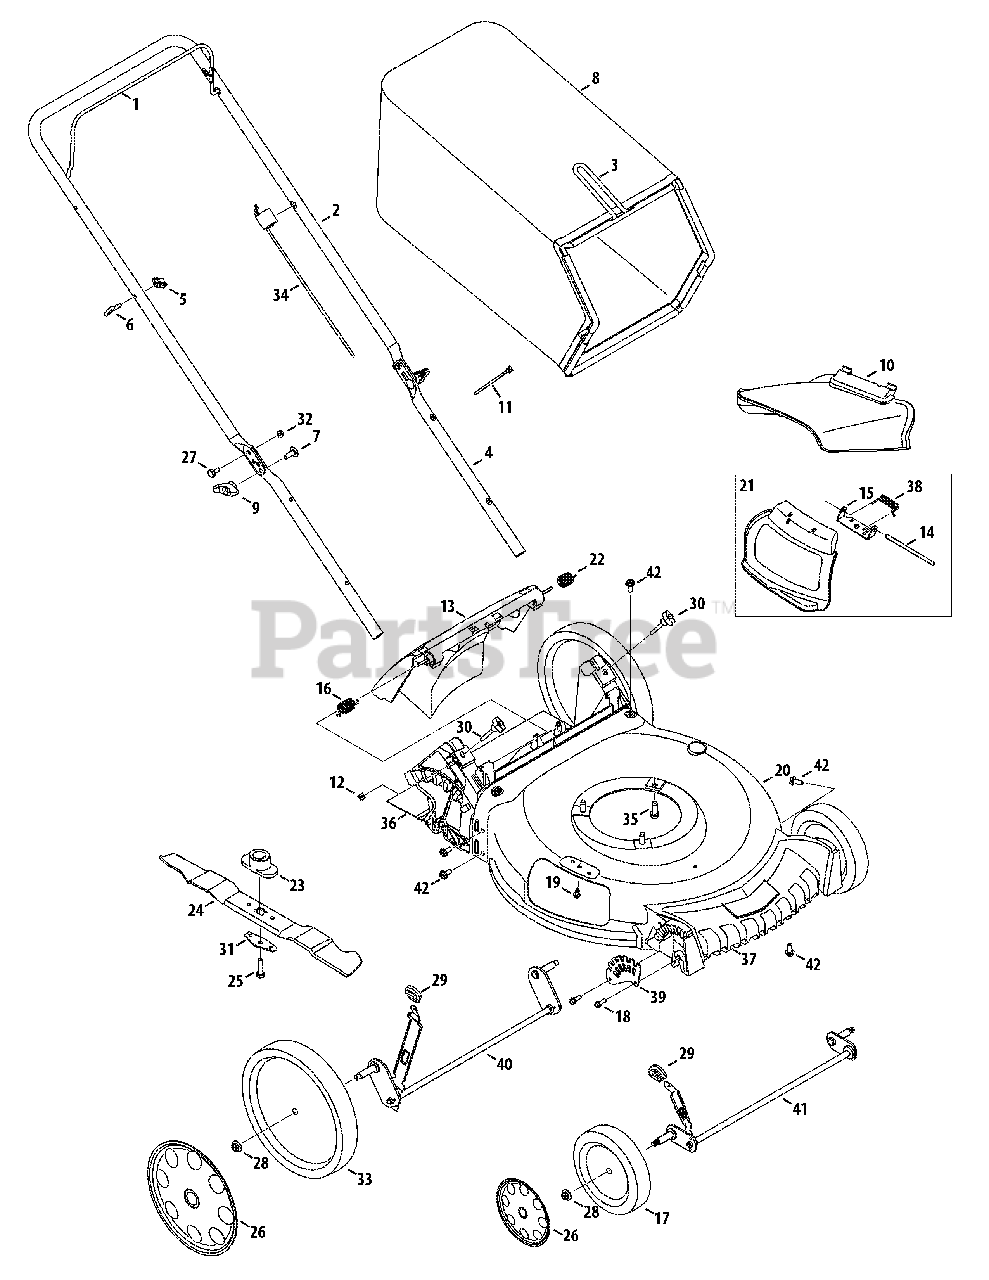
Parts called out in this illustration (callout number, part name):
1	Blade Control
2	Upper Handle
3	Grass Catcher Frame
4	Lower Handle
6	Rope Guide
7	Carriage Screw, 5/16-18
8	Grass Bag
10	Side Chute w/Flap
11	Cable Tie
12	Nut, Sq., 1/4-20
13	Rear Discharge Door & Baffle Assembly-Generic
13	Rear Discharge Door & Baffle Assembly-Lowes
14	Hinge Pin
15	Chute Deflector Bracket
16	Torsion Spring - RH
17	Front Wheel
18	Screw, 1/4-15 x .750
19	Screw, 1/4-20 x .500
20	Deck, 21"
21	Hinged Mulch Plug Assembly
22	Torsion Spring - LH
23	Blade Adapter
24	Mulching Blade
25	Screw , 3/8-24 x 1.50
26	Hub Cap - Front
26	Hub Cap - Rear
27	Sldr. Screw, .375 x .126 x 1/4-20
28	Flange Lock Nut, 3/8-16
29	Adjustment Lever Knob
30	Wing Nut
31	Blade Bell Support
32	Nut, Flange Lock, 1/4-20
33	Rear Wheel
34	Control Cable
35	TT Sems Screw, 3/8-16 x 1.0
36	Trail shield
37	Front Cover
38	Torsion Spring
39	Front Height Adjuster Plate
40	Rear Axle Assembly
41	Front Axle Assembly
42	Screw, 5/16-14 x .750
